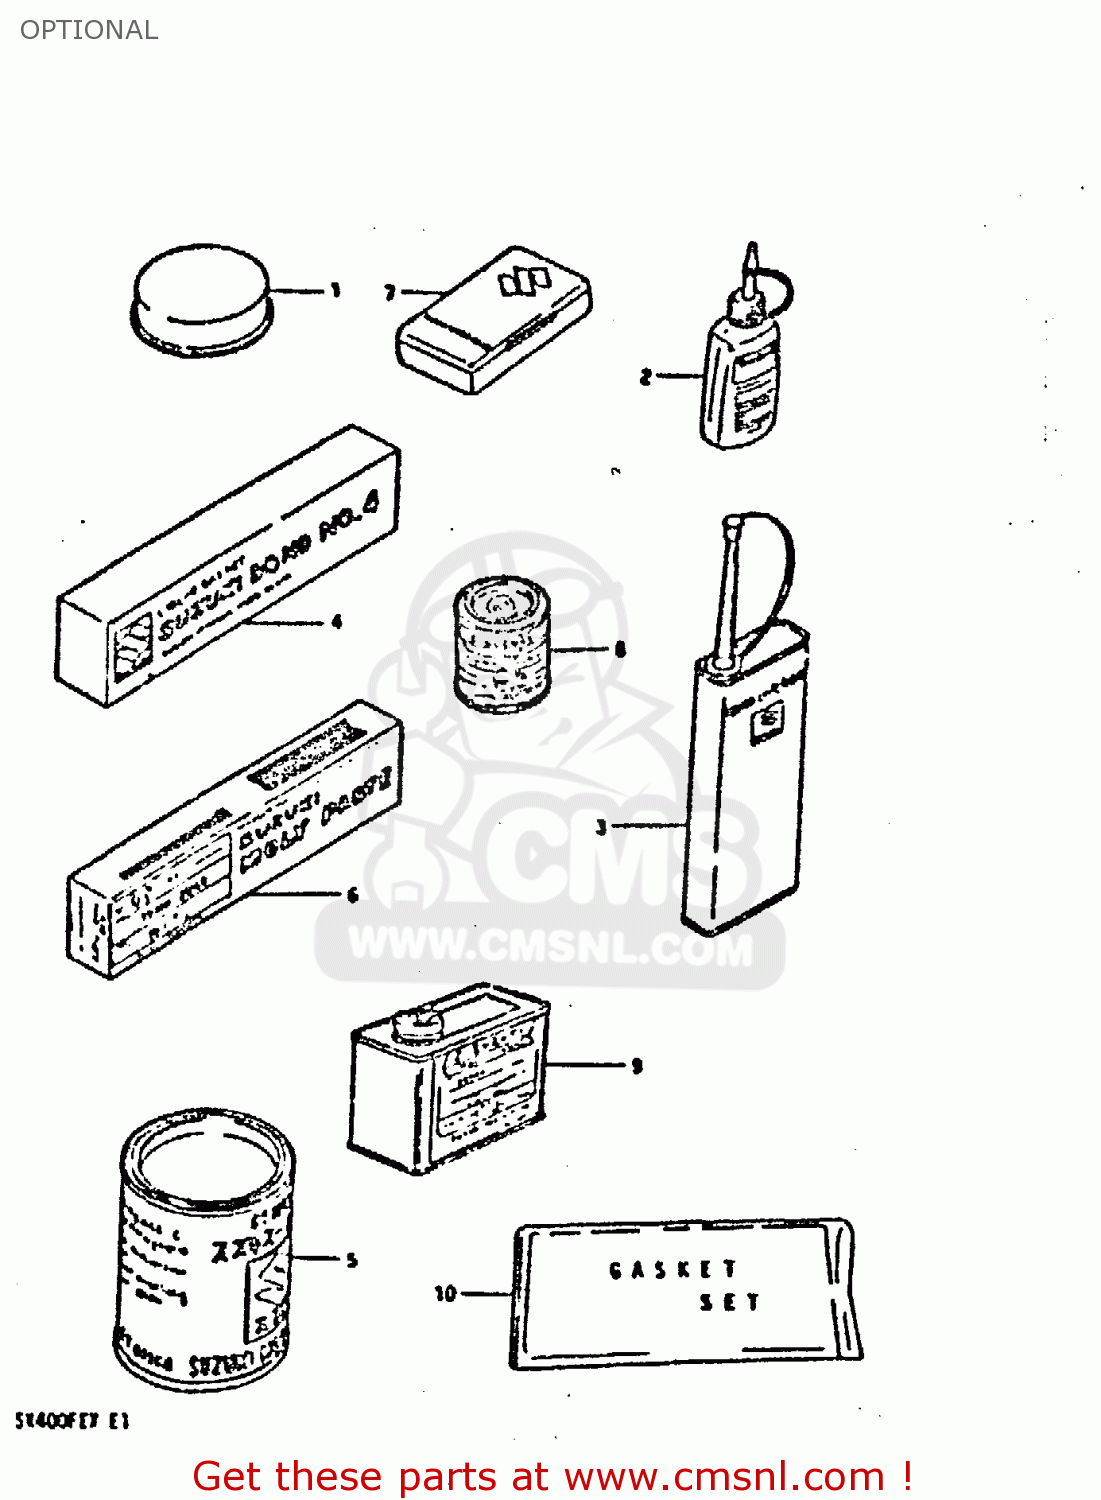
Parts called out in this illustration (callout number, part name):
1	GREASE,PBC FOR BRK PAD 20G
2	THREAD LOCK SUPER (1332B)
3	THREAD LOCK NO.1401 CLEAR 200G
4	BOND 1104
5	GREASE(C)EP2 LITHIUM 150G
6	SUZUKI MOLY PASTE
7	TUBE REPARING TOOL
8	PAINT,BLACK
9	PAINT (BLACK)
10	GASKET SET (MCA)
